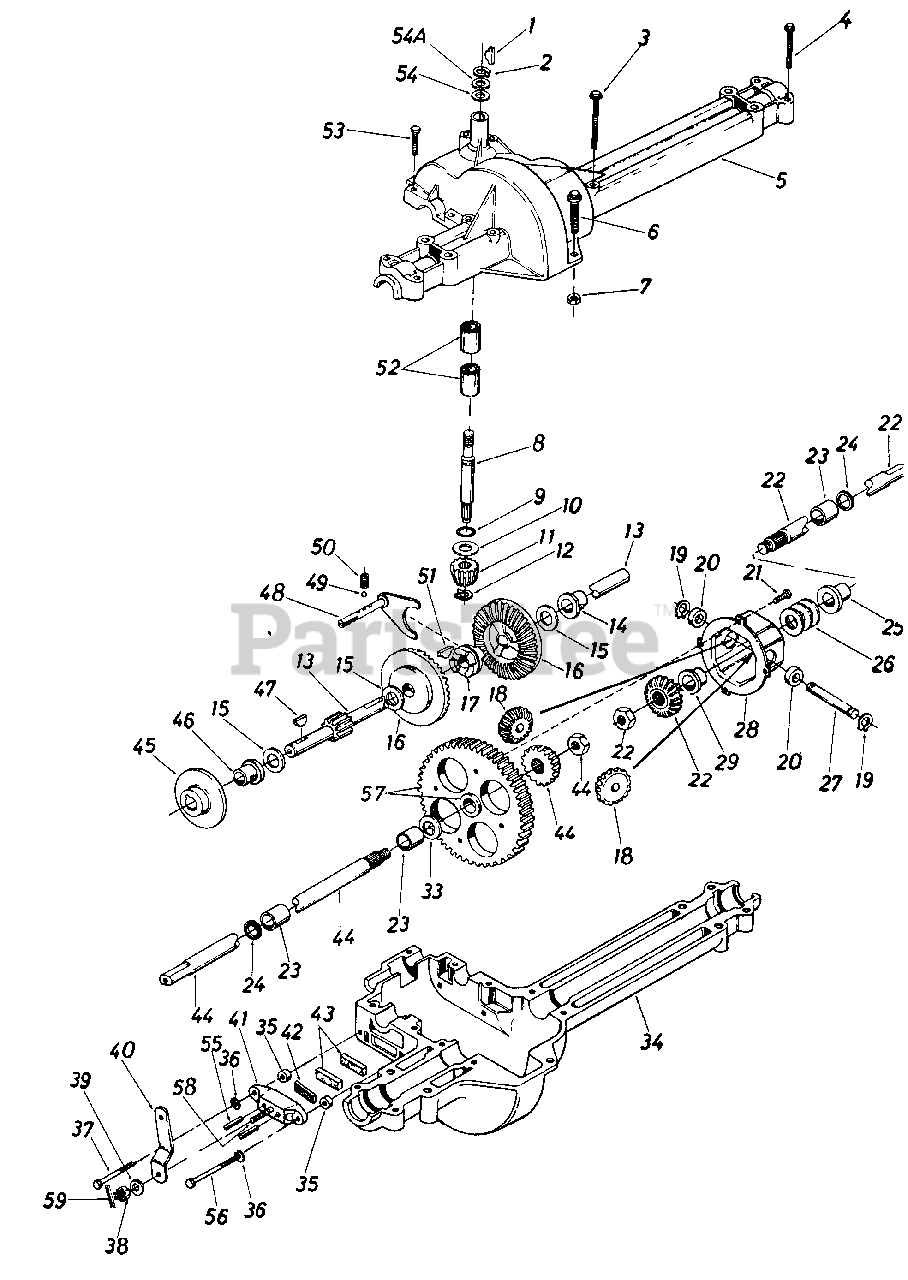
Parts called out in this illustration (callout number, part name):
1	#4 Hi-Pro Key 3/32 x 5/8" Dia.
2	Snap Ring .625" Shaft
3	Hex Bolt 1/4-20 x 1.75" Lg*
4	Hex Bolt 1/4-20 x 1.25" Lg.
5	Upper Housing
6	Hex Fl-Bolt 1/4-20 x .88" Lg.
7	Hex Nut 1/4-20 Thd.
8	Input Shaft
9	Square Seal 5/8" I.D.
10	Thrust Washer 5/8" I.D. x 1 25 O'D
11	Plnlorl Input 14T
12	Retaining Ring 7/16" Ext.
14	Flange Brg. 5/8" I.D. x 3/4" Lg.
15	Fl-Wash.
16	Bevel Gear 42T
17	Clutch Collar
18	IMiter Gear 15T (H.D.)
19	Snap Ring
20	IThrust Bearing 1/2" I.D. x 1.0" O.D.
21	Pan Head Scr. 1/4-20 X .50" Lg. w/ Patch
22	Axle R.H. Ass'y. Kit
23	Sleeve Bearing 3/4" I.D. x 1.0" Lg.
24	Oil Seal 3/4" I.D.
25	Flange Bearing 3/4" I.D. x 15/16" Lg.
26	Fl-Wash. .760" I.D. x 1.49" O.D.
27	Cross Shaft
28	Differential Housing Ass'y.
33	Fl-Wash. .760" I.D. x 1.49' O.D.
34	Lower Housing
35	Spacer .53" O.D. x 3/8" Lg.
36	L-Wash. 1/4" I.D.
37	Hex Bolt 1/4-20 x 1.50" Lg. (Grade 5)
38	Castle Nut 5/16-24 Thd.
39	Fl-Wash. .344" I.D. x .875" O.D.
40	Actuating Arm
42	Puck Plate
43	Brake Puck
44	Axle L.H. Ass'. Kit
46	Flange Bearing 5/8" I.D. x 15/16" Lg.
47	Woodruff Key 3/16 x 5/8 HT
48	Shift Fork Ass'y.
49	Ball Detent .250" Dia.
50	Spring Detent
51	#9 Hi-Pro Key 3/16" x 3/4" Dia. HT
52	Needle Brg. 5/8" I.D. x 1/2" Lg.
53	Hex Bolt 1/4-20 x 1.00" Lg.
54	Fl-Wash. 5/8" I.D. x .030
54A	Fl-Wash. 5/8" I.D. x .040
55	Actuating Pin 5116" Dia.
56	Hex Bolt 1/4-20 x 2.50" Lg. (Grade 5)
57	Differential Gear 72T Ass'y. w/ Bearing
58	Sq. Hd. Bolt 5/16-24 Thd.
59	Cotter Pin 3/32" Dia. x .50"
